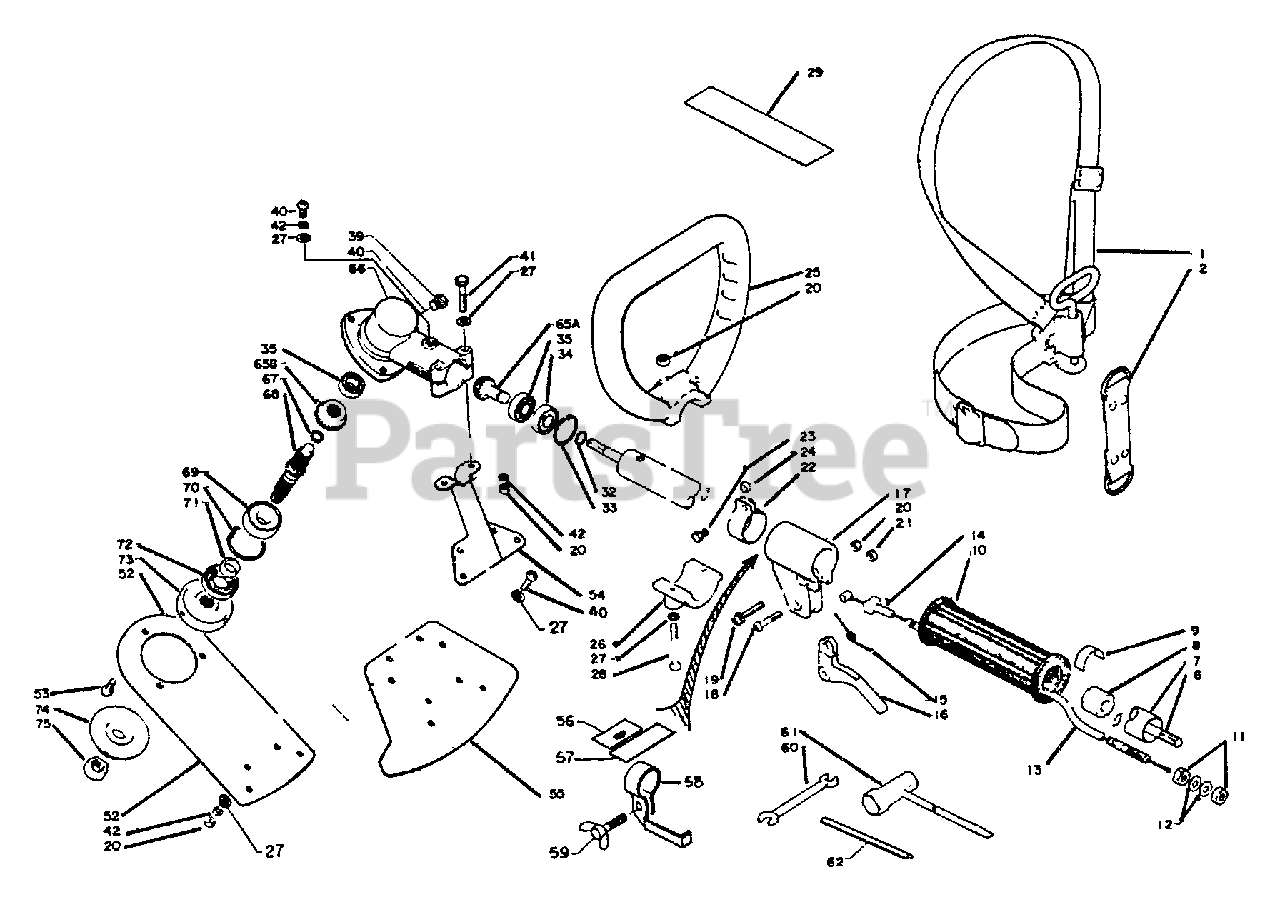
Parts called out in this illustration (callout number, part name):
1	SHOULDER STRAP ASSY
2	STRAP
6	DRIVESHAFT
7	MAIN PIPE ASSY
8	STOPPER
9	LABEL - ALIGNMENT
10	GRIP
12	WASHER 6.5×11.5×0.8
13	CABLE, THROTTLE
14	GUIDE, CABLE
15	SPRING, THROTTLE
16	TRIGGER, THROTTLE
17	BRACKET, TRIGGER
19	SCREW 5×28
20	NUT M5
21	LOCKNUT - 5
23	BOLT - 5×10
24	SPACER, GUARD
25	LOOP HANDLE ASSY
26	LOOP HANDLE ASSY
27	WASHER, FLAT 5.5×10×0.8
28	SCREW 5×40
29	LABEL
32	RING, RETAINING
33	RING, SNAP Ø25
34	BEARING, BALL 609
35	BEARING, BALL 609
39	BOLT - 8×6
40	SCREW 5×10
41	BOLT 5×35 SP
42	WASHER, SPRING 5
52	BRACKET
53	SCREW 5×10
54	BRACKET, SHIELD
55	SAFETY GUARD
56	LABEL
57	LABEL
58	BRACKET
59	BOLT - 5×14
60	SPANNER 8×10
61	WRENCH, T 17×19 MM
62	TOOL, LOCKING 5×120 MM
65	GEAR SET
65A	GEAR SET
65B	GEAR SET
66	CASE, GEAR
67	RING, RETAINING - 12
68	GEAR, SHAFT
69	BEARING, BALL - 6201 C3
70	RING, SNAP Ø32
71	SPACER 11.8×15×9
72	SEAL, OIL 22
73	PLATE, ADAPTER - UPPER
74	PLATE, ADAPTOR - LOWER
